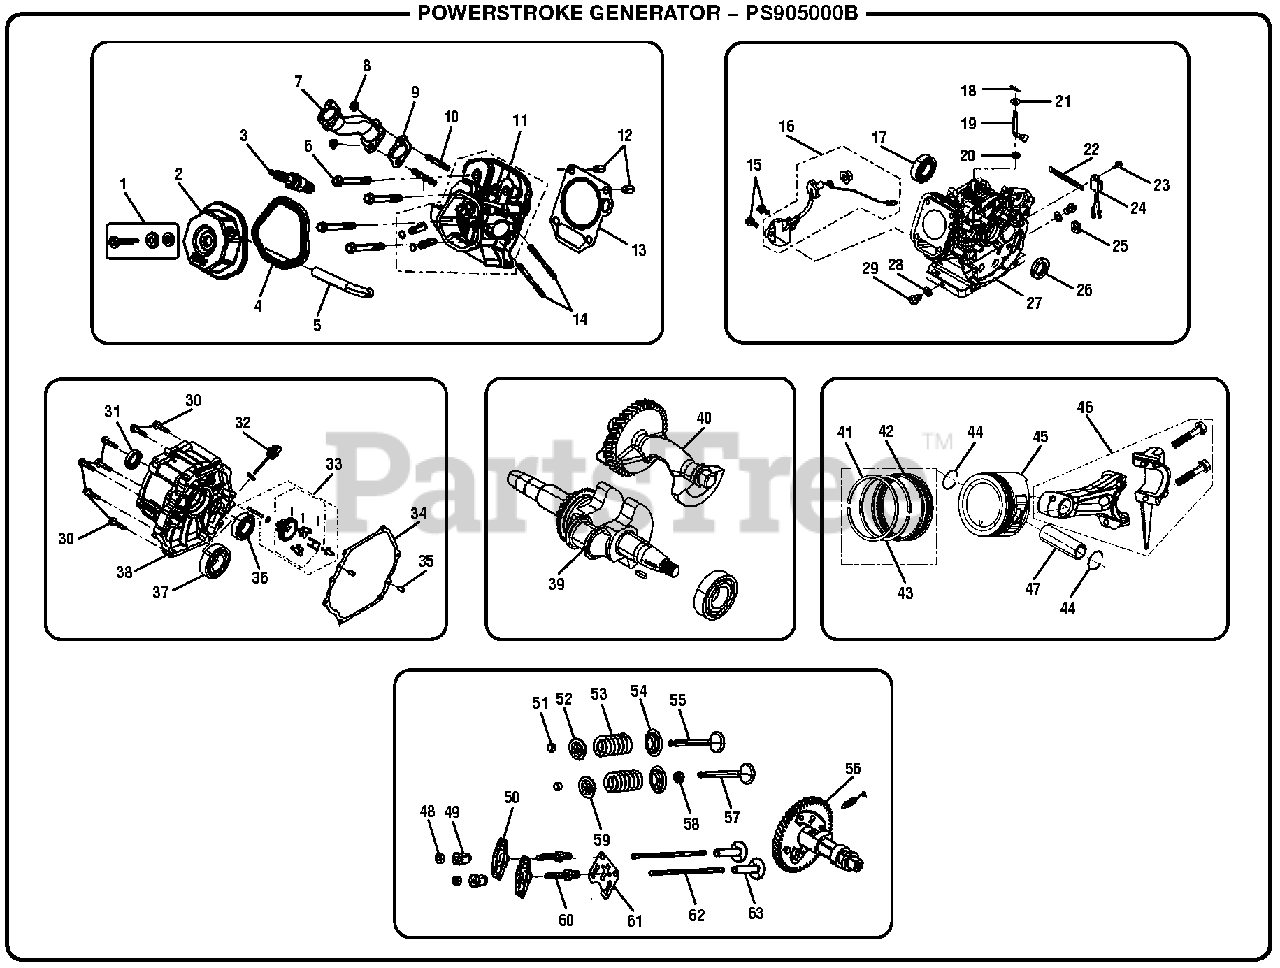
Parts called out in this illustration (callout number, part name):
2	Cylinder Head Cover
3	Spark Plug
4	Cylinder Head Cover Gasket
5	Breather Tube
7	Exhaust Pipe
9	Exhaust Outlet Gasket
10	Threaded Stud
11	Cylinder Head Assembly
13	Cylinder Head Gasket
14	Threaded Stud
16	Engine Oil Sensor
17	Ball Bearing
18	Pin
19	Governor Arm
24	Oil Protector
27	Crankcase Assembly
32	Oil Dipstick Assembly
33	Governor Gear Assembly
34	Crankcase Gasket
36	Ball Bearing
37	Ball Bearing
38	Crankcase Cover
39	Crankshaft Assembly
40	Balancing Shaft
41	The First Ring
42	Oil Ring Kit
43	The Second Ring
44	Piston Pin Clip
46	Connecting Rod
48	Valve Lock Nut
49	Valve Adjusting Nut
50	Valve Rocker
51	Valve Rotator
52	Exhaust Valve Retainer
53	Valve Spring
54	Valve Spring Retainer
55	Exhaust Valve
56	Camshaft Assembly
57	Intake Valve
59	Valve Spring Seat
60	Valve Adjusting Bolt
61	Stop Plate Assembly
62	Valve Lifter Assembly
63	Valve Tappet
